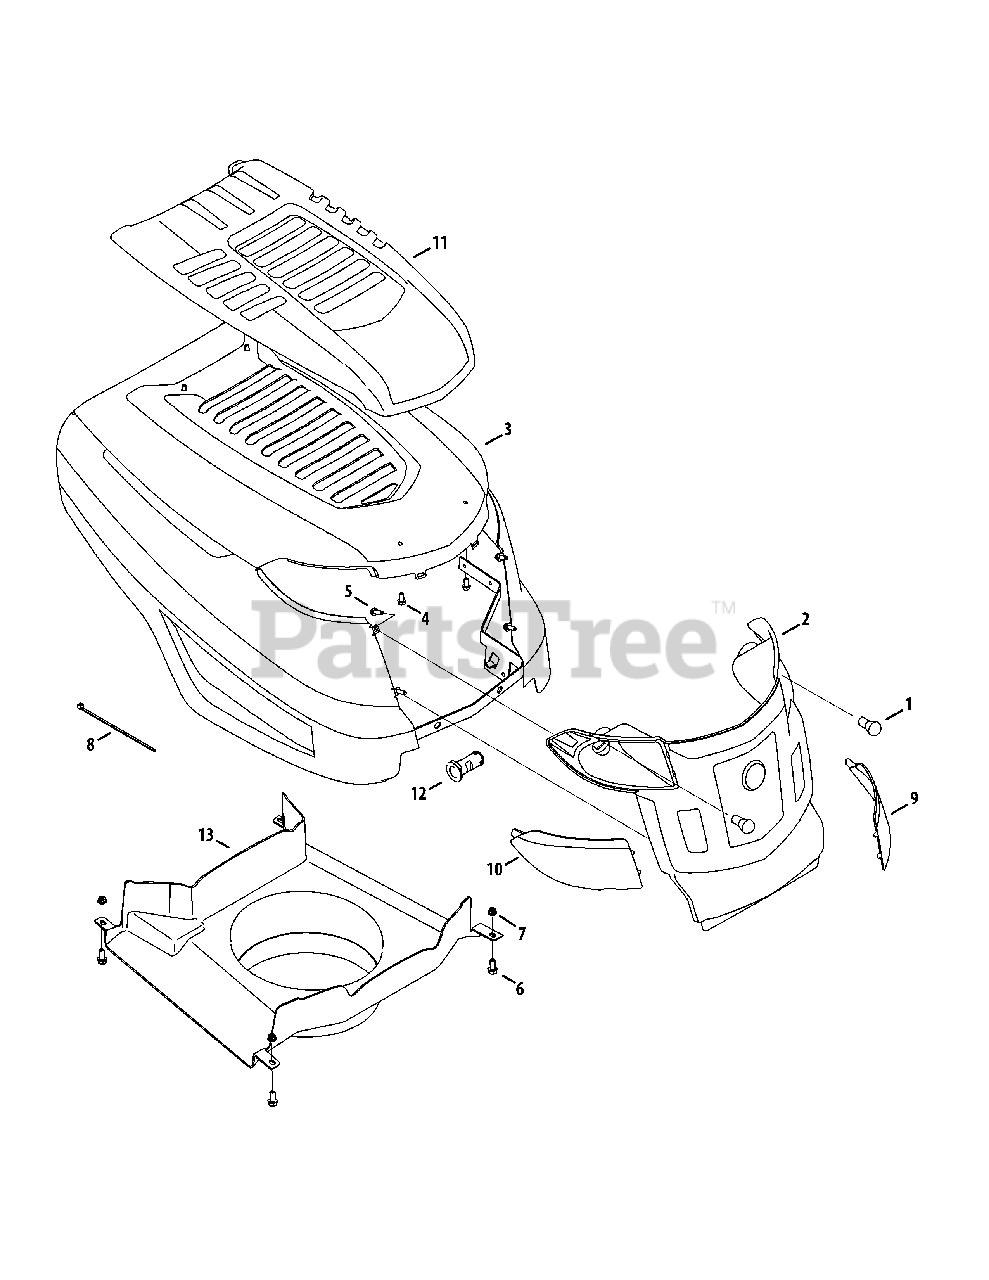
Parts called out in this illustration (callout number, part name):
1	Miniature lamp 12V socket
4	Screw, 1/4-15 x 0.50
5	Screw, 1/4 x .750
6	Hex Cap Screw, 1/4-20 x .62
7	Nut, Flange Lock, 1/4-20, Nylon
8	Cable Tie
9	Grill Lens - LH
10	Grill Lens - RH
13	Plenum
